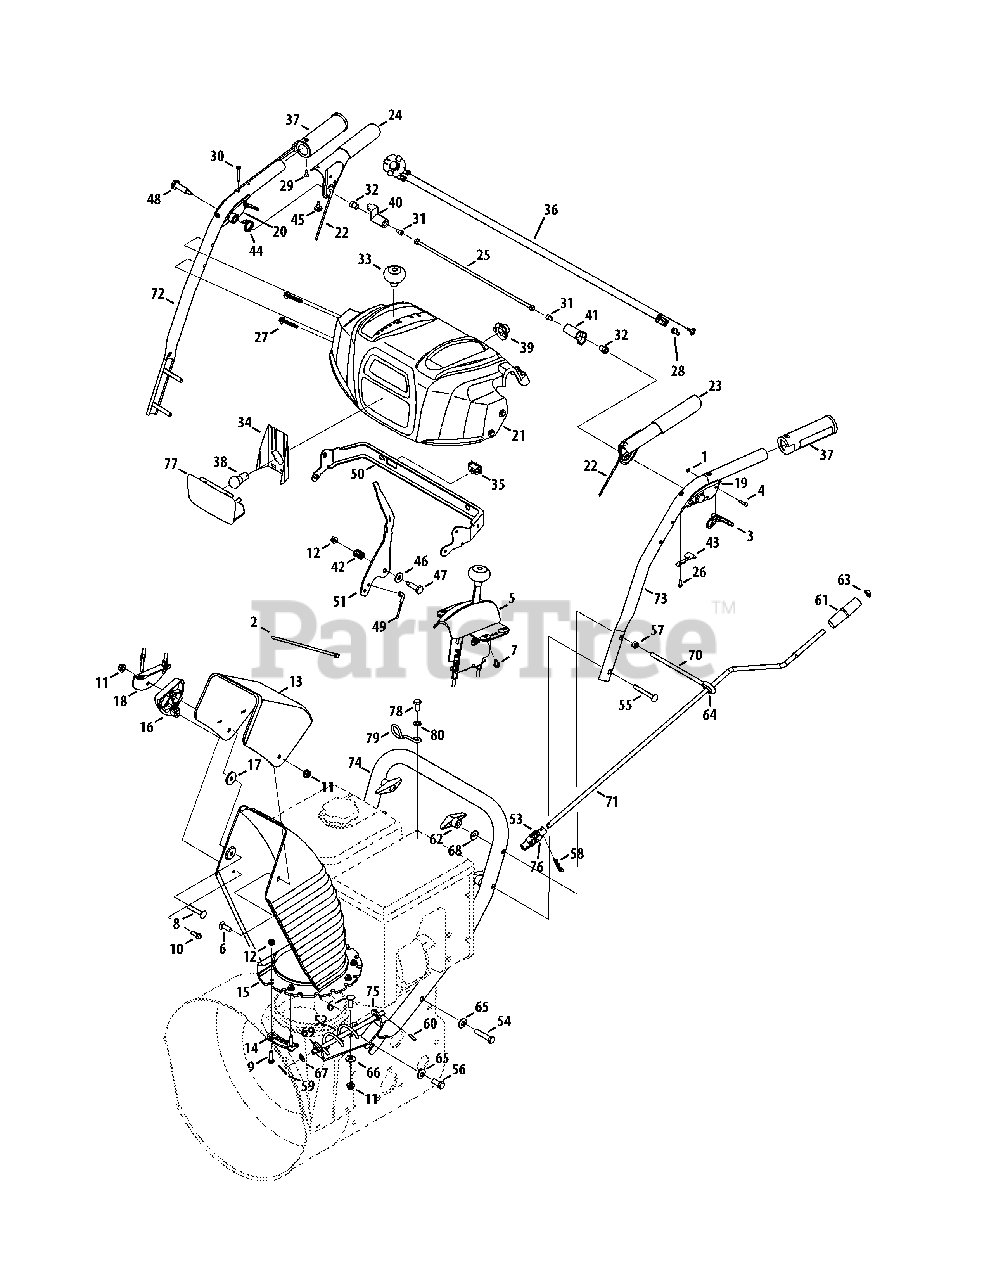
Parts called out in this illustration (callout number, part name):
2	Cable Tie
3	Trigger Lock
5	Chute Control Assembly
6	Carriage Screw, 5/16-18 x 1.0
7	Screw, 1/4-15 x .50
8	Carriage Screw, 5/16-18 x 1.75
9	Hex Screw 1/4-20 x 1.0
10	Screw, 1/4-15 x .750
11	Flange Lock Nut 5/16-18
12	Flange Lock Nut 1/4-20
13	Upper Chute, 6.0
14	Chute Flange Keeper
15	Lower Chute
16	Cbl. Guide, Chute Tilt
17	Flat Wash, .344 x 1.125 x .12
18	Cable Bracket
19	Handle Assembly, LH
20	Handle Assembly, RH
21	Handle Panel
22	Cable Ass’y, Auger/Drive
23	Engagement Handle, LH
24	Engagement Handle, RH
25	Clutch Lock Rod Assembly
26	Screw, #8-16 x .50
27	Screw, 1/4-20 x 1.625
28	Hex Screw, 1/4-20 x .5
29	Screw, #10-16 x .625
30	Screw, #10-24 x 1.375
31	Screw, 1/4-20 x .50
32	Nut, Hex, 1/4-20
33	Shift Knob
34	Lens Lable
35	Heated Grip Switch
36	Wire Harness
37	Heated Grip
38	Lamp, 12.8V
39	Light Socket
41	Clutch Lock Cam
42	Compression Spring
43	Clutch Lock Spring
44	Torsion Spring, .8156 ID x .3038
45	Rubber Bumper
46	Flat Washer, .385 x .87 x .06
47	Screw, Shldr., .374 x 1.05
48	Screw, Shldr., .437 x 1.345
49	Clutch Cable
50	Panel Bracket
52	Chute Crank Assembly
53	Joint Block Assembly
54	Hex Screw, 3/8-16 x 2.00
55	Carriage Screw, 5/16-18 x 2.5
56	Screw, Hex, 3/8-16 x 1.00
57	Nut, Hex, 5/16-18
58	Internal Cotter Pin
59	Internal Cotter Pin
60	Spring Pin, .156 dia. x .875 Lg.
61	Knob, Crank
62	Wing Knob, 5/16-18
63	Push Cap, 3/8
64	Rubber Grommet
65	Bell Wash, .375 x .87 x .063
66	Flat Washer, .349 x .879 x .063
67	Flat Wash, .375 x .738 x .063
68	Wash, Bell, .34 x .872 x .06
69	Plastic Bushing, .38 ID
70	Eye Bolt, .70 Dia.
71	Chute Rod, .375 Dia. x 29.72
72	Handle, Upper, RH
73	Handle, Upper, LH
74	Handle, Lower
75	Chute Crank Bracket
76	Roll Pin, 3/16 Dia. x 1.100
78	Hex Screw, M8-1.25
79	Cable Guide
80	Flat Washer, .330 x .630 x .0635
